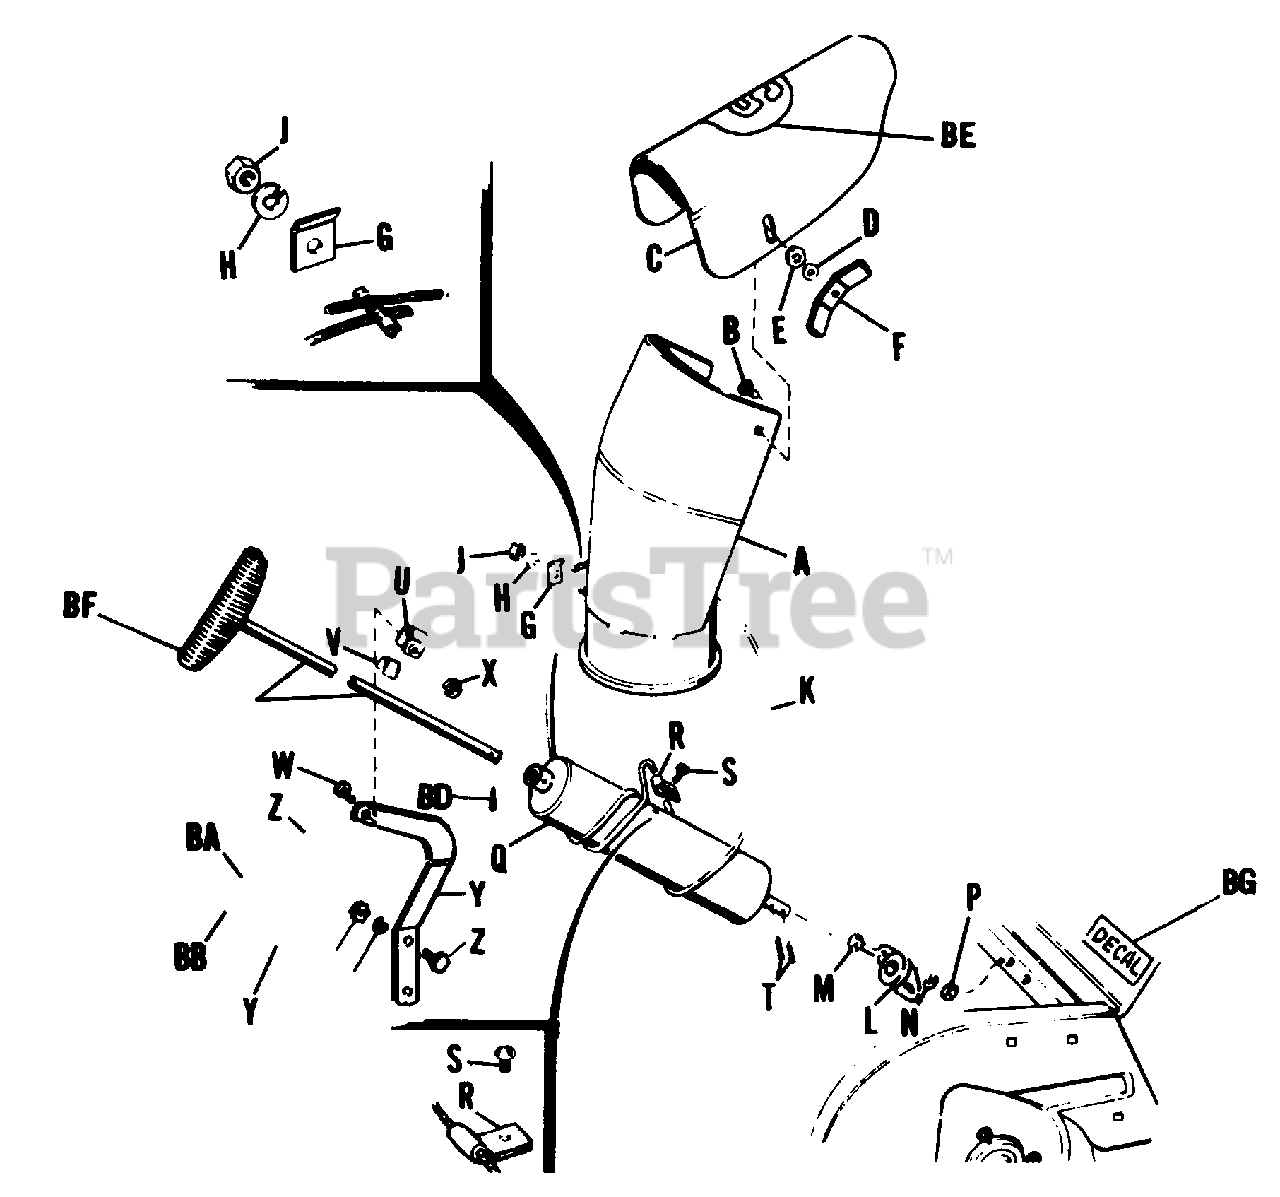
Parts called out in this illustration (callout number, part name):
A	Spout Assembly
B	Carriage Bolt, 5/16"-18 x 3/4"
C	Spout Extension
D	Washer, Plain 3/8"
E	Washer, Lock 3/8"
F	NUT, Wing, 5/16-18
H	Washer, Lock 5/16"
J	Nut, Hex Full 5/16"-18
K	Spout Cord
M	Capscrew, Hex, 1/4"-20 x 5/8"
N	Washer, Lock 1/4"
P	Nut, Hex, Full 1/4"-20
Q	Tube Assembly Spout Control
S	Self-Tapping Screw, 1/4"-20 x 3/8"
T	Cotter Pin 1/8" x 3/4"
V	Liner, Guide
W	Capscrew Hex 5/16"-18 x 1/2"
X	Nut, Hex, Full Lock, 5/16-1
Y	Rod Guide Support
Z	Hex. Capscrew 3/8-16x 1 lg.
BA	Lock Washer, 3/8
BB	Hex Nut, Full, 3/8"-16
BC	Handle Assembly
BD	Cotter Pin 5/32 x 1" lg.
BF	Cover Handle
